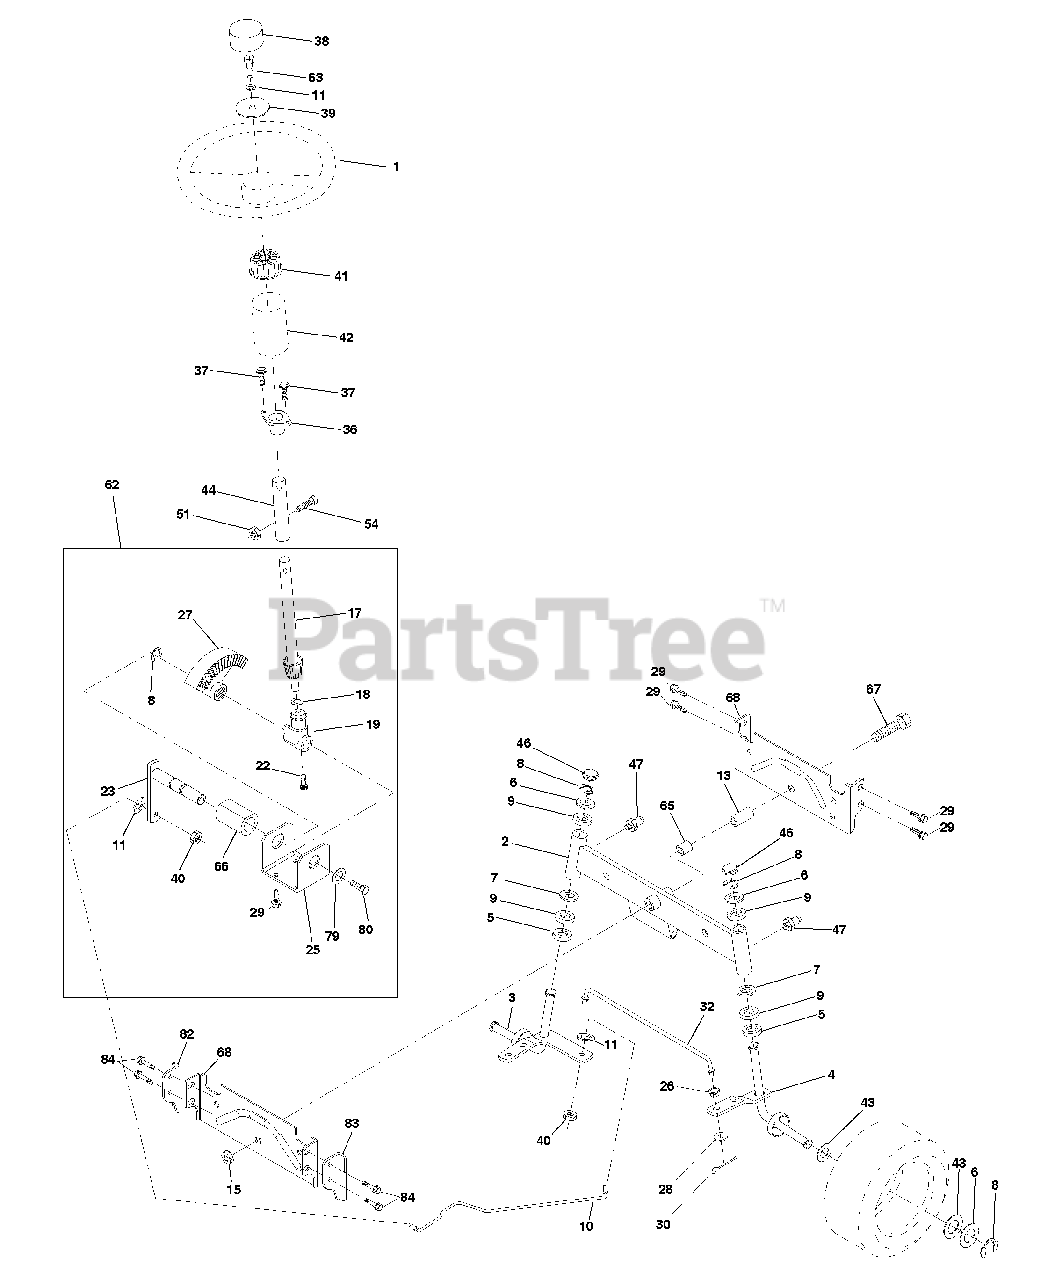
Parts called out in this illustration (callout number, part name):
1	Wheel Steering
2	Axle Asm STMP Dropped STL
3	Spindle Asm LH
4	Spindle Asm RH
5	Bearing Race Thrust Harden
6	Washer 25/32 X 1-5/8 X 16 Ga
7	Washer 27/32 X 1-1/4 X 16 Ga
8	Ring Klip #t5304-75
9	Bearing Col Strg Blk
10	Link Drag Extended Stamp
11	Washer Lock Hvy Hlcl Spr 3/8
13	Bearing Axle STLT/GT
15	Nut Lock Flange 5/8-11 Unc
17	Shaft Asm Strg
18	Washer Thrust 515x 750x 033
19	Support Shaft
22	Screw Hex Wsh Hd Torx
23	Shaft Asm Pittman
25	Bracket Steering
26	Bushing Link Drag Blk LR
27	Gear Sector
28	Washer 13/32 X 7/8 X 16 Ga
29	Screw Thdrol 3/8-16x3/4 Ty-tt
30	Pin Cotter 1/8 X 3/4 Cad
32	Rod Tie Wire Form 19 75 Mech
36	Bushing Strg
38	Insert Cap Strg Wh Au
39	Washer 13/32 X 2-3/8 X 8 Ga
40	Lock nut
41	Adaptor Wheel Strg
42	Boot Steering Shaft
43	Washer 25/32 X 1 1/4 X 16 Ga
44	Extension Steering Shaft LR/LT
46	Cap Spindle Fr Top Blk
47	Fitting Grease
51	Nut Lock Hex w/Ins 5/16-18
54	Bolt Fin Hex 5/16-18 Unc x 1-1/4
62	Kit, Steering Assembly Svc
63	Bolt Fin Hex 3/8-16unc x 1 Gr. 5
65	Spacer Axle
66	Bearing Arm Pittman
67	Bolt, Fin Hex 5/8-11 UNC x 2-3/4
68	Axle, Brace
79	Washer 13/32 x 1-1/4 x 12 Ga.
80	Bolt Hex Nylon 3/8-16 x 3/4
82	Bracket Brace Front Axle LH
83	Bracket Brace Front Axle RH
84	Screw Thdrol 3/8-16 x 1
